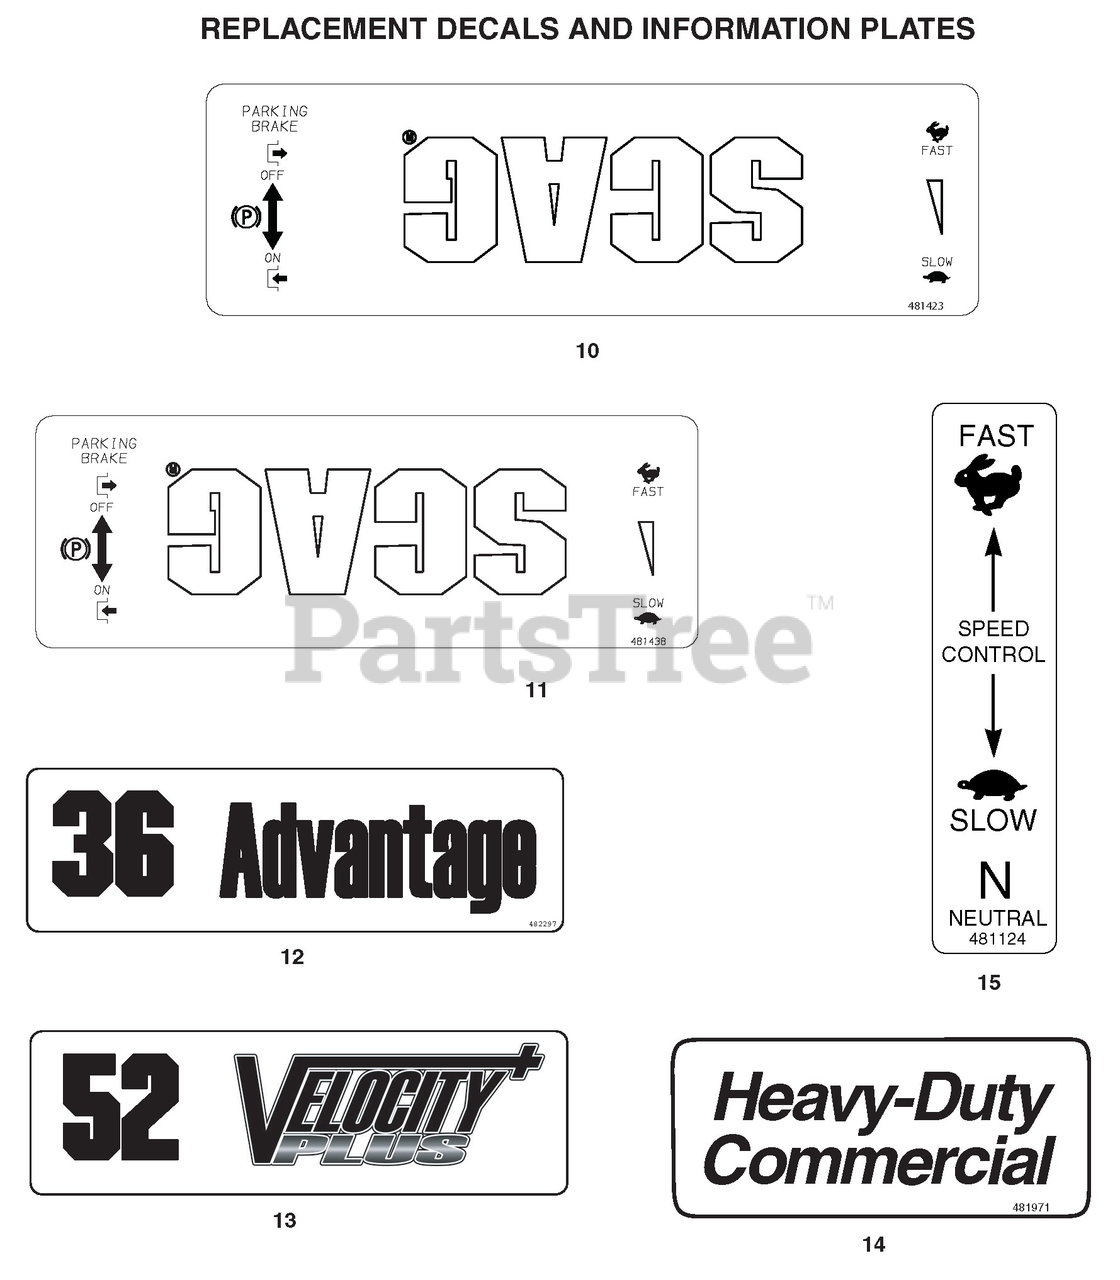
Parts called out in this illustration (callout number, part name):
10	Decal, Instrument Panel - Front (SWZ-18FS & SWZ-22FSE only)
11	Decal, Instrument Panel - Front
12	Decal, 36 Advantage
13	Decal, 48 Velocity Plus
13	Decal, 52 Velocity Plus
13	Decal, 61 Velocity Plis
14	Decal, Heavy Duty Commercial
15	Decal, Speed Control
